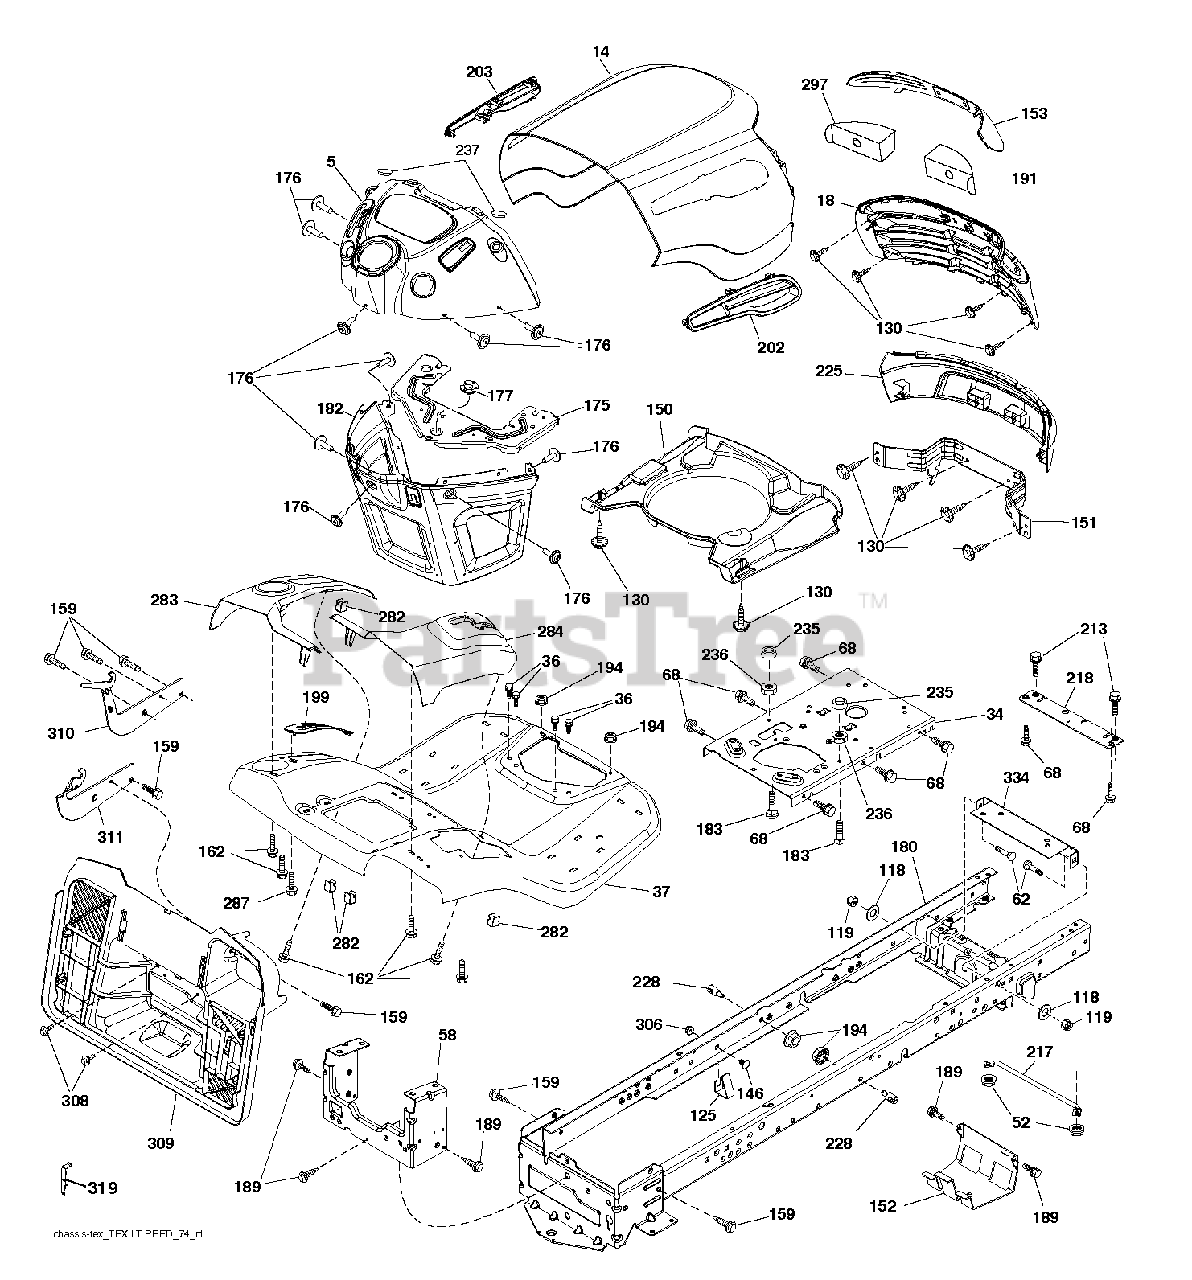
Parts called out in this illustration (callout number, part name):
36	SCREW 5/16"
52	LOCKNUT
58	DRAWBAR UPPER 2PC SMALL FENDER
119	LOCKNUT
125	Fuel Line Clip
130	SCREW.#10 X 0.750.BOS THREAD
146	BOLT.RDHD.SHT.SQNK.3
151	BRACKET.PIVOT.ALPHA.LT
152	SHIELD BROWNING
159	SCREW, 3/8-16X3/4
162	SCREW.HI-LO.CONSOLE
175	CROSSMEMBER
176	SCREW.#10-24X5/8.RN.QU
177	BUSHING STEERING
182	DASH.LWER.PREDATOR/HUSQ.LT
183	BOLT.5/16-18X1-1/4 FULL THD
189	SCREW
191	INSERT.REFLECT.PREDATOR.LT.RH
194	NUT LOCK HEX FLANGE 5/16-18
213	BOLT
217	ROD.PIVOT.HOOD
218	X-PIECE.HOOD.STOP.NON/
228	STUD.FASTNER.W/ANTI-ROTATE
235	SPACER FENDER
236	NUT.CENTERLOCK.5/16-
237	PLUG.MOUNT.CARGO.BLK
282	CLIP.RETAINER.CONSOLE.LT.HUSQ
297	REFLECTOR.INSERT.PRED.LH.LT
306	NUT LOCK FLG 3/8-16 UNC
308	BOLT, 5/16-18 X 1 3/4
